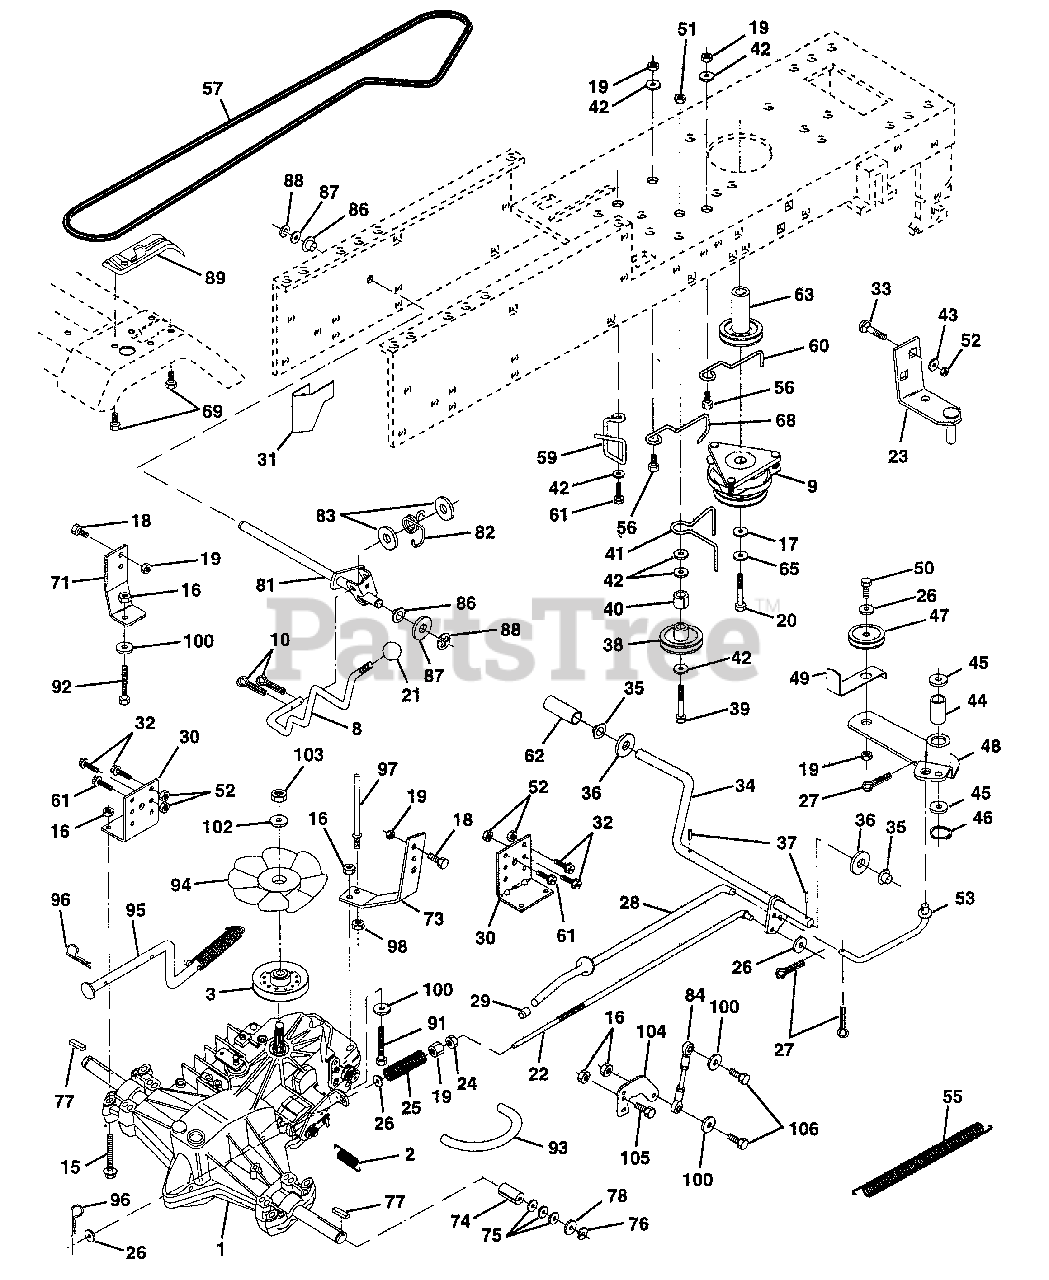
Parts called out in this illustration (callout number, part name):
1	Transaxle w/cas Hydro 310-0650
2	Spring, Return, Brake
3	Pulley, Transaxle Hydro 750 LT
8	Rod Shift Hydro LT
9	Clutch Elecric
10	Pin Cotter 1/8 x 1 CAD
15	Bolt Hex 5/16-18 Unc Flghd
16	Nut Lock Hex W/Ins. 5/16-18 Unc P
17	Washer 1-1/2 OD x 15/32 ID x .250
18	Bolt Fin Hex 3/8-16 Unc x 1 Gr.5
19	Nut Lock Hex W/Ins 3/8-16 Unc
20	Bolt, Hex 7/16-20 x 4-1/4 Ga. 5
21	Knob Deluxe 1/2-13 UNC BLK/BLK
22	Rod, Brake Hydro
23	Bracket Asm Mtg CL
24	Nut Hex Jam 3/8-16 UNC
25	Spring, Brake Rod
26	Washer
27	Pin Cotter 1/8 x 3/4 CAD.
28	Rod, Parking Brake
29	Cap,Parking Brake
30	Bracket, Transaxle
31	Keeper Belt Lh
32	Bolt Hex Hd 5/16-18 Unc x 3/4
33	Bolt Carriage 5/16-18 UNC x 3/4
34	Shaft, Foot Pedal 20.500
35	Bearing, Nylon
37	Pin, Roll
38	Pulley, Idler, Flat
40	Spacer Split
41	Keeper, Belt Retainer
42	Washer 13/32 x 13/16 x 12 Ga
43	Washer 11/32 x 5/8 x 12 Ga.
44	Bearing, Nylon
45	Washer, Hardened
46	Ring, Klip
47	Pulley, Idler, V-Groove Plastic
48	Bellcrank Assembly
49	Retainer, Belt Style Spring
50	Bolt
52	Nut Crown Lock 5/16-18 ,
53	Link, Clutch
55	Spring, Return, Clutch
56	Bolt, Fin Hex 3/8-16 UNC x 1 1/4
57	V-Belt, Ground Drive
59	Keeper, Center Span
60	Keeper Belt Engine
61	Screw Thdrol. 3/8-16 x 3/4 Ty. TT
62	Cover, Pedal Premium
63	Pulley, Engine
65	Washer Lock Hvy HLCL Spr 7/16
68	Keeper Belt Engine
71	Strap Torque Lh Hydro 18/20" T
73	Strap Torque Rh Hydro 18/20" T
74	Spacer, Split
75	Washer 25/32 x 1-1/4 x 16 Ga.
77	Key, Square
78	Washer 25/32 x 1-5/8 x 16 Ga
81	Shaft Asm. Cross Hydro 20" Tires
82	Spring Torsion T/A
83	Washer 17/32 x 3/4 x 16 Ga.
84	Rod, Tie Hydro 20" Tires SPH Ball 4.75
86	Bushing Rod Strig. 629/632 ID
87	Washer 21/32 x 1-1/4 x 16 Ga.
88	Ring Klip #5304-62
89	Console, Hydro YT/GT Fender
91	Bolt Fin Hex 5/16-18 x 2-1/4
92	Bolt Fin Hex 5/16-18 Unc x 1-1/2
93	Line Fuel Hydro 4"
94	Fan, Hydro 7"
95	Control Asm. Bypass Hydro
96	Retainer Spring 1" Zinc/Cad
97	Keeper Belt Rh Hydro 0750.18/20"
98	Nut Keps Hex 3/8-16 Unc
100	Washer 11/32 x 3/4 x 16 Ga.
102	Washer Belleville .501 D x 1.50D
103	Nut Hex Jam Toplock 1/4-20 Unf
104	Arm, Control Hydro
105	Screw Cap Hex 5/16 x 18 x 1
106	Bolt Fin Hex 5/16-18 Unc x 1-1/4
